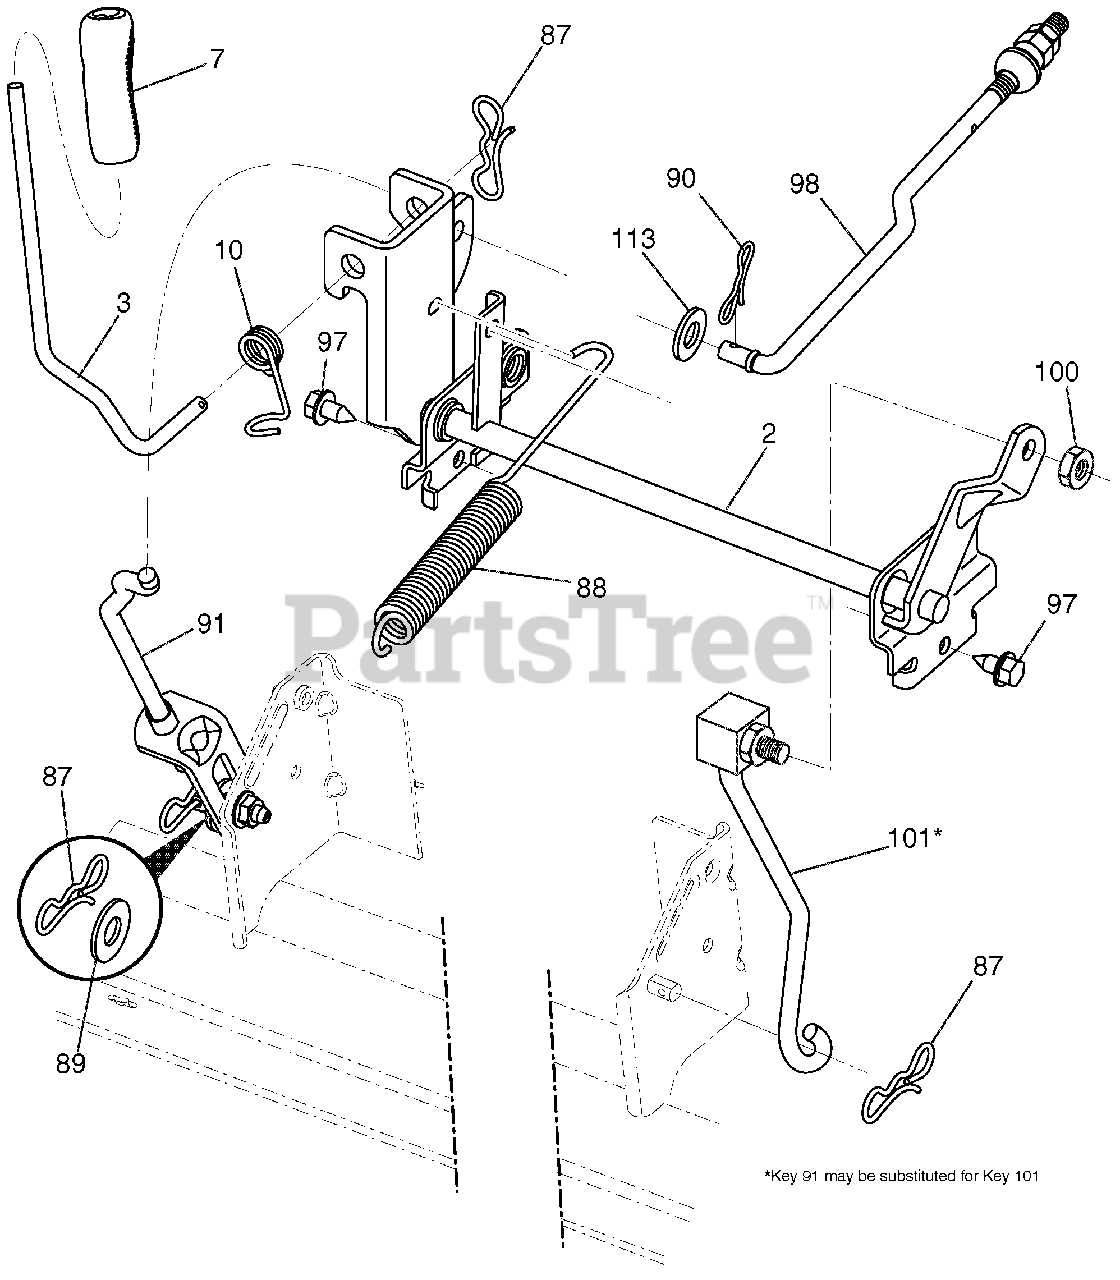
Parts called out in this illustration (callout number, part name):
2	SHAFT ASM., LIFT
3	LEVER.LIFT.HANDLE.LT
7	GRIP.LEVER..5625 ID.BLACK 428
10	SPRING.TORSION.HANDLE.LIFT
87	PIN.COTTER.7/16.BOW TIE LOCK
88	SPRING.LIFT ASSIST
89	WASHER.17/32 X 1-3/16 X 12 GA.
90	PIN.COTTER.5/16.BOW TIE LOCK
91	LINK ASM.LIFT.LH.REAR
97	SCREW.HEXWSH THDR3/8-16X3/4.BL
98	LINK ASM.SUSP.FRONT.MWR.11
100	NUT.CENTERLOCK.3/8-16 UNC.
101	LINK ASM.LIFT.FIXED.38/42/46"
113	WASHER.CLEAR ZINC
